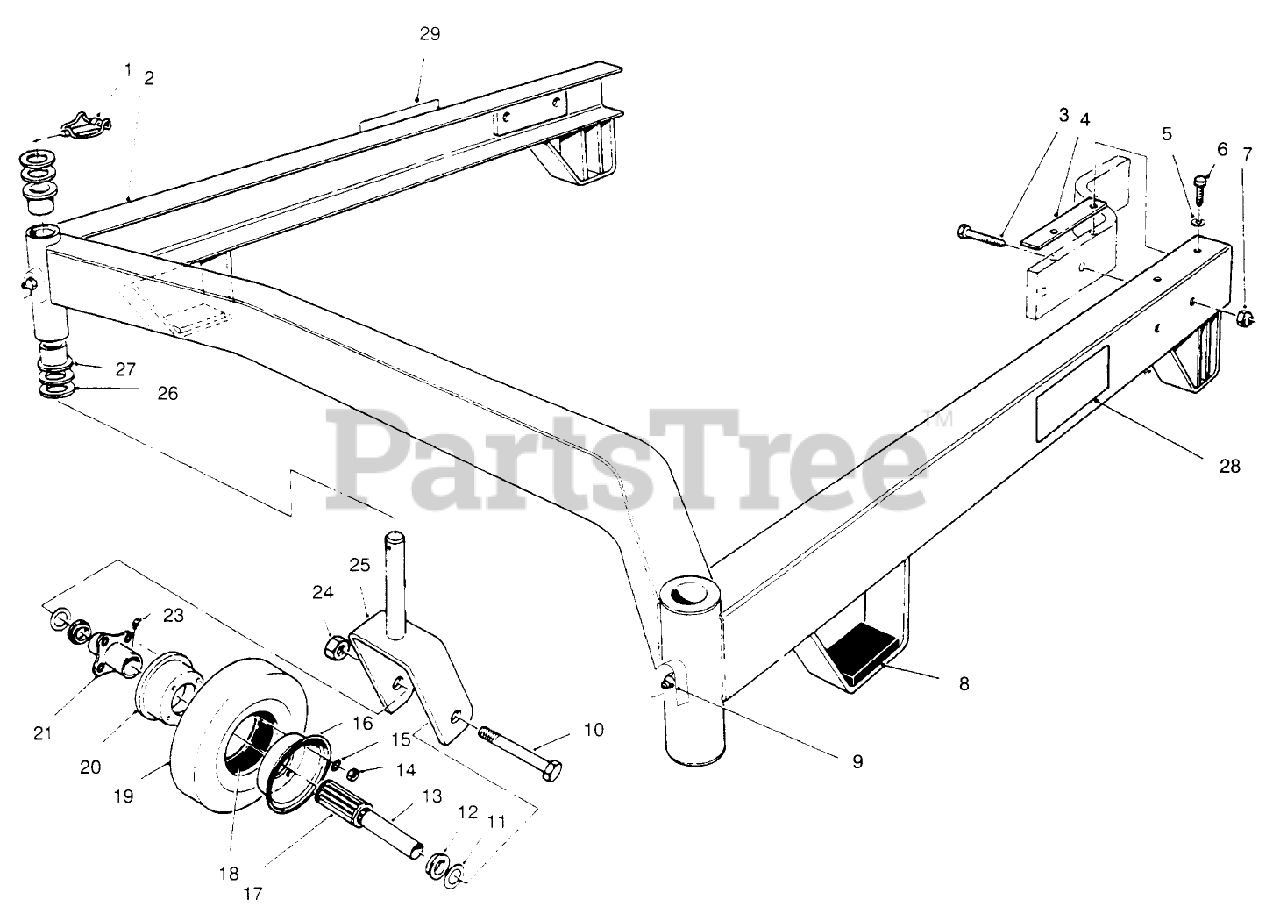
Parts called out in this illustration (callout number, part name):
1	PIN-LYNCH
2	SUSPENSION ASM
3	SCREW-HH
4	SHIM-CARRIER
5	WASHER-FLAT
6	SCREW-HHF
7	NUT-LOCK, SIDE
8	CUSHION-RUBBER
9	FITTING-GREASE
10	SCREW-HH
11	WASHER-FLAT
12	BEARING-OUTSIDE
13	SPANNER-TIRE
14	NUT-HEX
15	WASHER-LOCK
16	MALE WHEEL HALF
17	BEARING-ROLLER
18	TUBE-INNER (W/VALVE)
20	FEMALE WHEEL HALF
21	HUB-CENTER
23	FITTING-LUBE, 45 DEG
24	NUT-HEX
25	Castor Fork
26	WASHER-THRUST
27	Bushing
28	Spacer
29	Spacer
